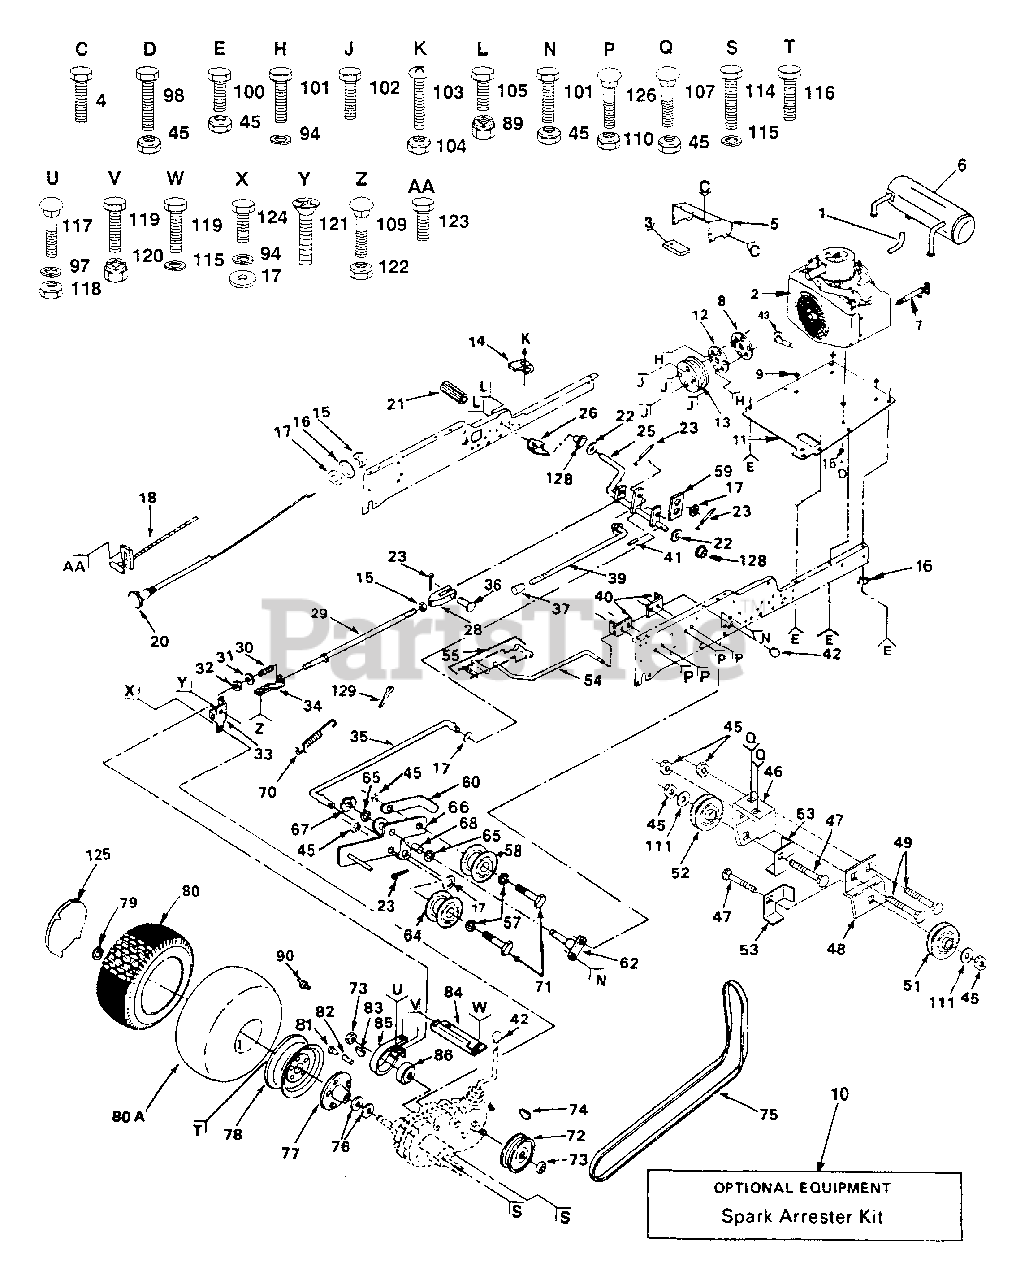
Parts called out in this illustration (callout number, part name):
1	Exhaust Tube Outlet
2	Engine-18HP Kohler M18QS Type 24644
3	Duct, Lower Assembly
4	Screw, Hex Thd. Cut 1/4-20 x 1/2
5	Duct, Exhaust, Upper
6	Muffler, Exhaust
7	Oil Drain Valve
8	Chaff Guard
10	Spark Arrester Kit
11	Base, Engine
13	Pulley, Ground Drive
14	Actuator, Switch, Interlock
15	Nut, Hex 3/8-24
16	Washer, Lock Ext. Tooth 3/8
17	Washer 13/32 x 13/16 x 16 Gauge
18	Control, Throttle
20	Control, Choke
21	Cover, Pedal
22	Washer 25/32 x 1-1/4 x 16 Gauge
23	Pin, Cotter 3/32 x 3/4
25	Shaft, Foot Pedal
26	Bracket, Interlock
29	Rod, Brake
30	Spring, Compression
31	Washer 13/32 x 1 x 14 Gauge
32	Locknut 3/8-24
33	Bracket, Brake
34	Guide, Rod, Brake
35	Rod, Clutch
36	Pin, Clevis
37	Cap, Plunger
39	Rod, Parking Brake
40	Bracket, Rod, Shift
41	Pin, Roll 3/16 x 1-1/4
43	Clip, Insulated
45	Locknut 3/8-16
46	Bracket, V-Pulley, Drive, Mule
47	Bolt, Carriage 3/8-16 x 1-3/4
48	Bracket, Idler, Flat
49	Bolt, Carriage 3/8-16 x 3/4
51	Idler, Flat
52	Pulley, Idler
53	Keeper, Belt
54	Rod, Shift, Hi-Lo
55	Connecting Link, Spring Clip
57	Washer 13/32 x 7/8 x 13 Gauge
58	Idler, Flat
59	Retainer, Spring
60	Retainer, Belt
62	Bracket Assembly, Clutch
64	Idler, Grooved
65	Washer, Hardened
66	Bracket, Clutch W/Bearing
67	Klip, Ring
68	Bearing, Idler
70	Spring, Extension
71	Bolt, Hex 3/8-16 x 1-3/4
72	Pulley, Transaxle
73	Locknut 1 /2-20
74	Key, Woodruff 3/16 x 5/8
76	Washer, Thrust, Axle
77	Bushing Assembly and Wheel Hub
78	Rim Ass'y. Rear
79	Klip, Ring
80	Tire, Rear
80A	Tube, Rear
81	Cap, Valve
82	Stem, Valve
83	Key, Woodruff #9 (3/16 x 3/4)
84	Bracket, Support, Transaxle
85	Band, Brake
86	Drum, Brake
89	Nut, Crownlock 1/4-20
90	Fitting, Grease
94	Washer, Lock 3/8
97	Washer, Lock 1/4
98	Bolt, Hex 3/8-16 x 1-1/4 Grade 5
100	Bolt, Hex 3/8-16 x 3/4
101	Bolt, Hex Head 3/8-16 x 1 Grade 5
102	Screw, Hex 5/16-18 x 1
103	Screw, Fin #10-24 x 1
104	Locknut #10-24
105	Bolt, Hex Head 1 /4-20 x 3/4
107	Bolt, Carriage 3/8-16 x 3/4 Grade 5
109	Bolt, Carriage 5/16-18 x 3/4
110	Locknut 5/16-18
111	Washer 13/32 x 1 x 12 Gauge
114	Bolt, Hex 7/16-14 x 1-1/4
115	Washer, Lock 7/16
116	Bolt, Hub
117	Bolt, Carriage 1/4-20 x 5/8
118	Nut, Hex 1/4-20
119	Bolt, Hex 7/16-14 x 1
120	Nut, Crownlock 7/16-14
121	Screw, Mach. Undrcut. Flat Head 3/8-1 6 x 3/4
122	Locknut 5/16-18
123	Screw, Hex 1/4-20 x 1/2
124	Bolt, Hex 3/8-16 x 7/8
125	Cover, Wheel
126	Bolt, Carriage 5/16-18 x 3/4
129	Pin, Cotter 1/4 x 1
